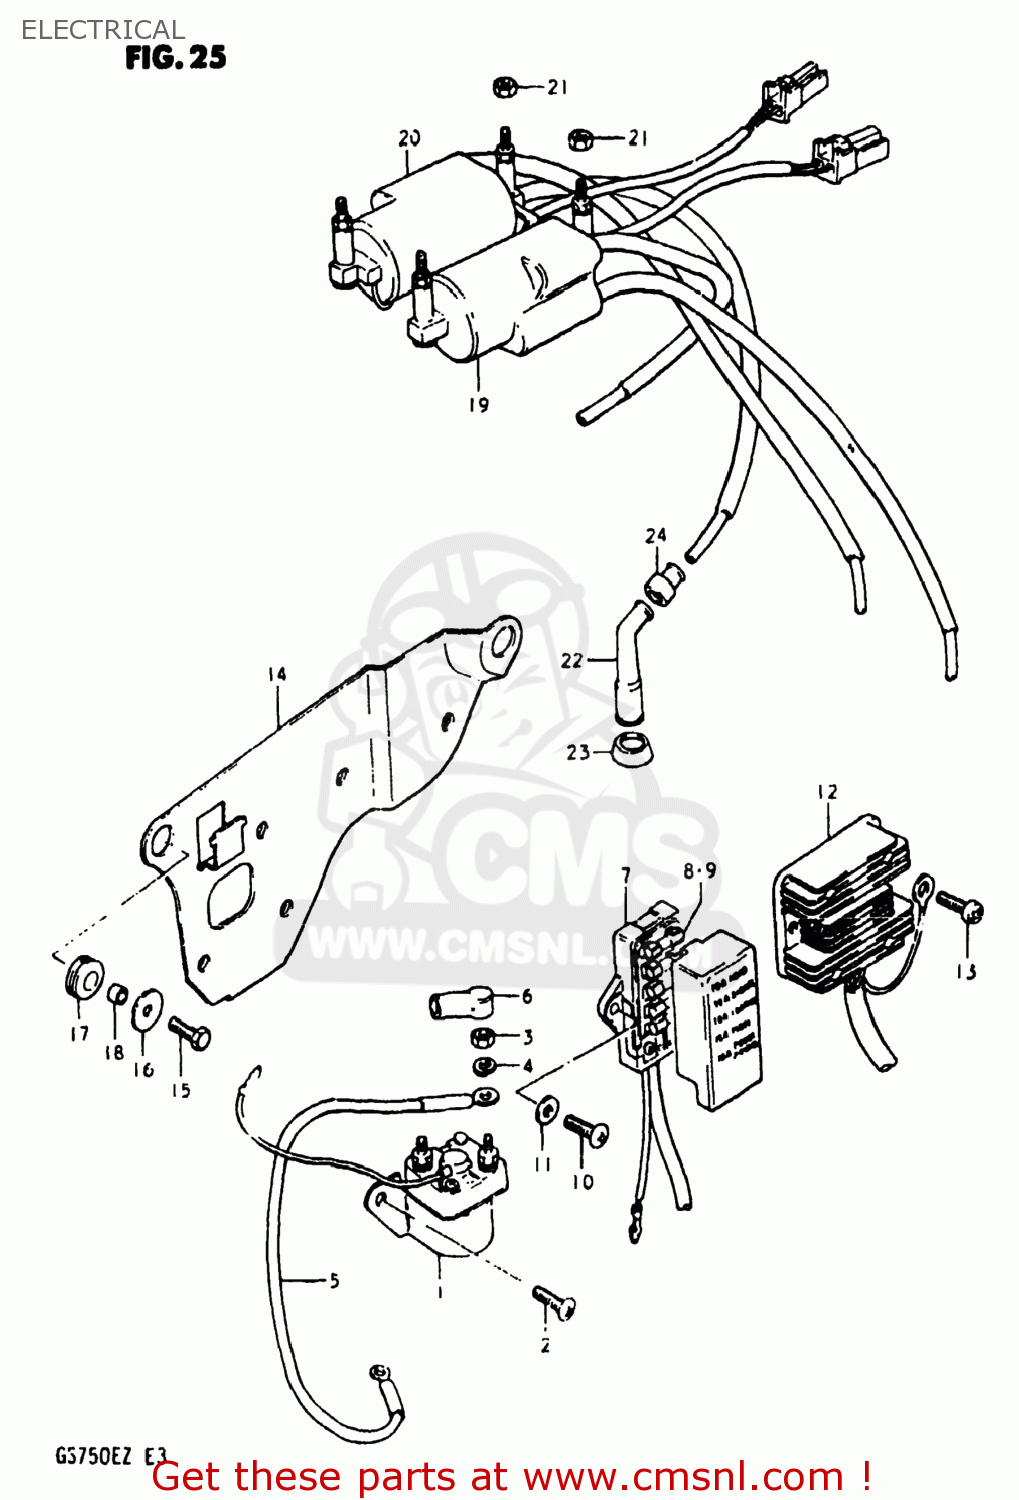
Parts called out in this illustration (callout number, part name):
1	RELAY ASSY,STARTING MOTOR
2	SCREW
3	NUT 6MM
4	LOCK WASHER
5	CORD,BATTERY MINUS
6	CAP,STARTER RELAY
7	BOX ASSEMBLY,FUSE
8	FUSE(10A)
9	FUSE(15A)
10	SCREW
11	WASHER
12	RECTIFIER ASSEMBLY
13	SCREW 6X12
14	PLATE,ELECTRIC PARTS HOLDER
15	BOLT, UPPER
16	WASHER(6,5X22X1.6)
17	CUSHION
18	SPACER (7X9X7)
19	COIL ASSEMBLY,IGNITION
20	COIL ASSEMBLY,IGNITION
21	NUT
22	CAP ASSY,SPARK PLUG
23	SEAL,SPARK PLUG
24	SEAL,SPARK PLU
